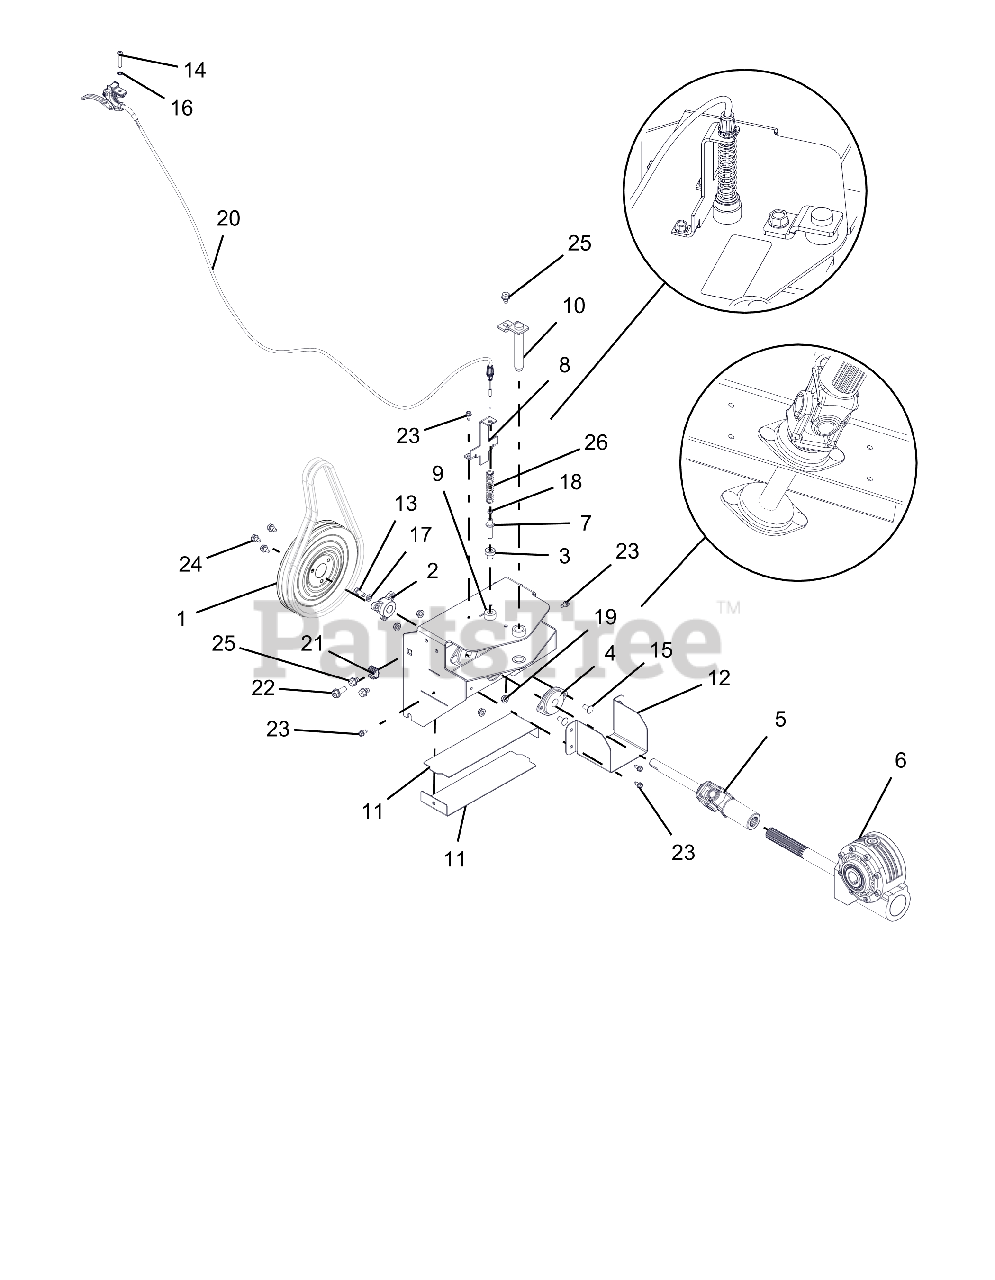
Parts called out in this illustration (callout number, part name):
1	PULLEY, SPIN FORM DUAL GROOVE
2	PULLEY HUB, BOLT-ON D-BORE .75
3	SPACER -FLANGED .390X.500X.781
4	BEARING, 2 BOLT FLANGE -.75 ID
5	DRIVELINE, SERIES 07 (U-JOINT)
6	GEARBOX, WORM - 8.25:1
7	PIN, ADJUSTABLE ANGLE BRUSH
8	BRKT, PIN HOLDER
9	ADAPTER, BRUSH
10	WLDMT, BRUSH PIN
11	GUARD, BRUSH PTO
12	GUARD, BRUSH U-JOINT
13	BLT-HEX .31-24X.75 YWZC GR5
14	SCR-MCH .25-20X1.50 OVAL HD
15	@BLT-RDHDSQNK .31-18X.75 G5YZ
16	WSHR-LK-INT .250 TH TYA
17	WSHR-LK .312X.097 HVY YWZC
18	@NUT-HEX 10-24 YWZC
19	@NUT-LK-TOP-FLG .31-18 YWZC
20	CABLE, REMOTE BRUSH LOCK
21	NUT-RETNR .38-16 TINRMAN
22	BLT-SERHFWH .375-16X1.0 YWZC
23	SCR-TAP .25-20X.50 HWH TR YWZ
24	@SCR-TAP .31-18X.50 HWH TR YWZ
25	@SCR-TAP .38-16X.50 HWH TR YWZ
26	SPRING, COMPRESSION
